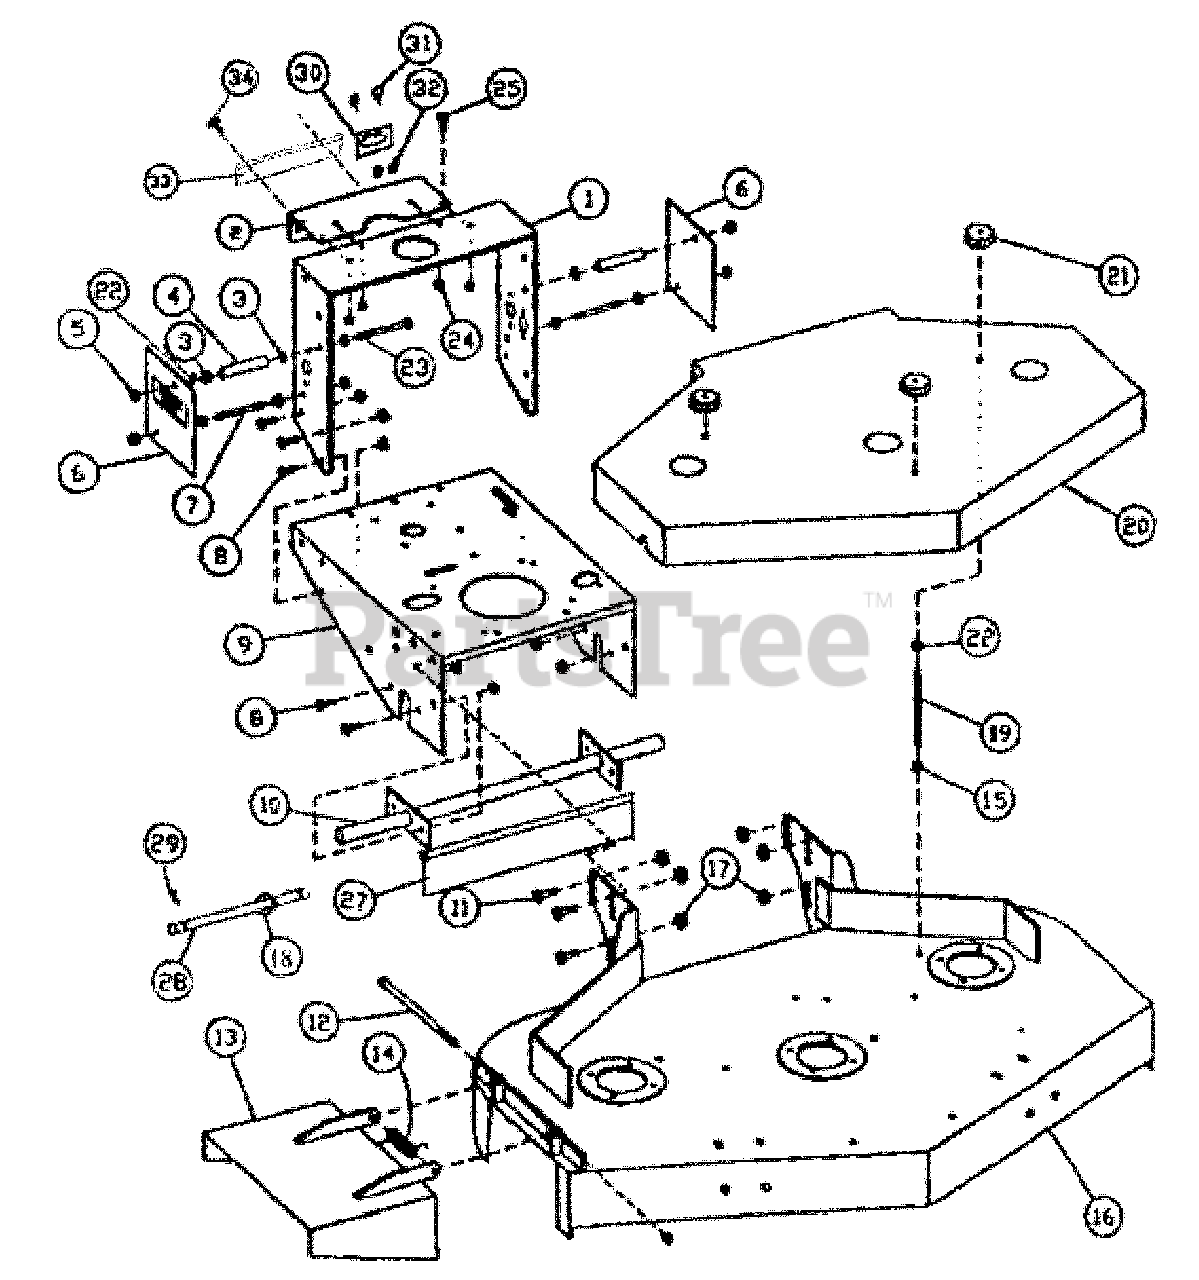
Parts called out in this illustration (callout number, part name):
2	100-002 SHIFT CONSOLE
3	100-003 WASHER
4	100-004 PIVOT TUBE
5	NUT, 200-001 M10
6	100-005 FENDER
7	BOLT, END 200-002 DBL.
8	M10X1.5X25MM HHB GR8.8
10	148-001 AXLE WLDT 48`
11	HHB 200-004 M12 25
12	200-005 HHB M10`240
13	100-007 CHUTE DEFLECTOR
14	100-008 TORSION SPRING
16	148-002 BLUE DECK 48
17	200-007 NYLON NUT M12
18	5/16STD FLAT WASHER.
19	200-015 HEX BOLT M10`140
21	100-009 SAUCER NUT
22	200-006 NYLON NUT M10
23	200-008 HEX.BOLT M10`110
24	200-009 NYLON NUT M6
25	200-011 BOLT M6`16
26	200-006 NYLON NUT M10
27	100-011 SAFETY FLAP
29	200-014 COTTER PIN 2`20
31	200-012 BOLT M5`15
33	100-116 SHIFT PLATE
34	200-063 RIVET 2`5
